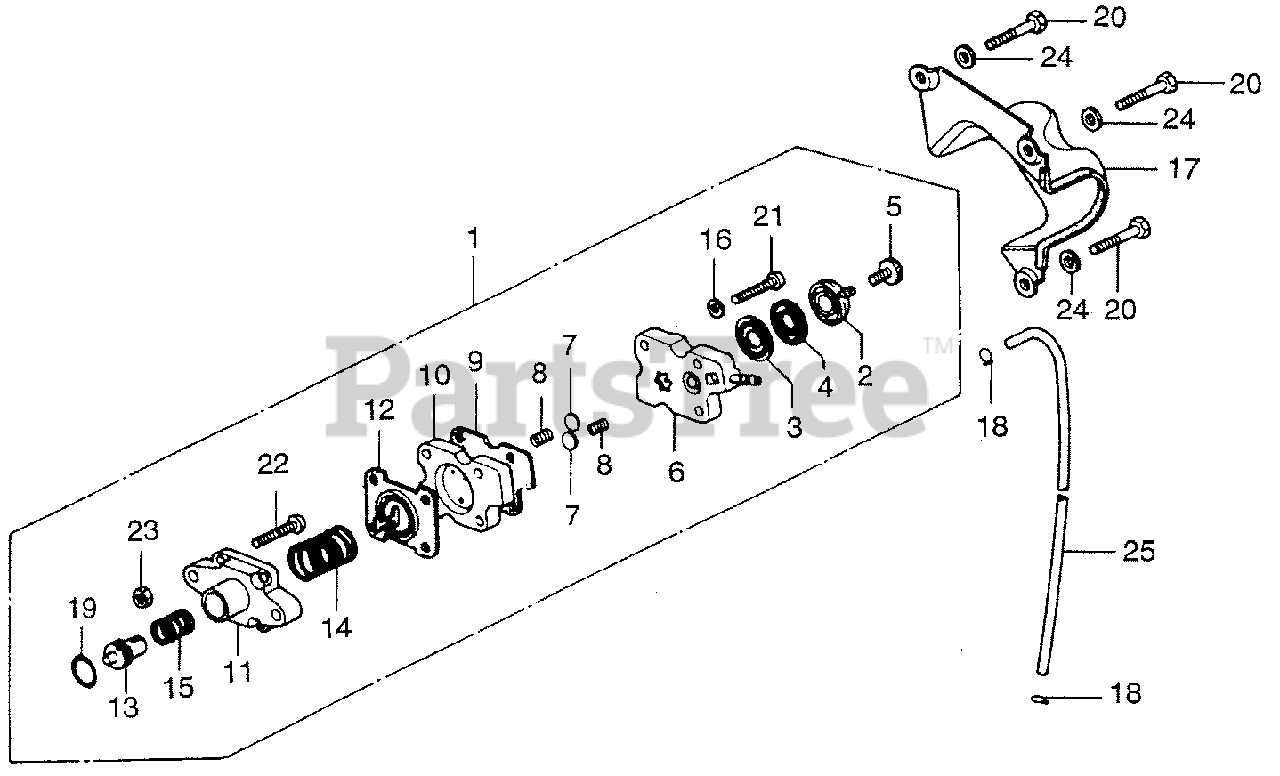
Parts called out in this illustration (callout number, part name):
1	PUMP ASSY., FUEL (NOT AVAILABLE)
2	BODY, FILTER (NOT AVAILABLE)
3	SCREEN (NOT AVAILABLE)
4	GASKET, SCREEN (NOT AVAILABLE)
5	SCREW, CAP (NOT AVAILABLE)
6	CAP (N/A: SEE ASSEMBLY) (ALT. PNO: 16700-935-325)
7	VALVE (NOT AVAILABLE)
8	SPRING, VALVE (NOT AVAILABLE)
9	GASKET, VALVE (N/A: SEE ASSEMBLY)
10	BODY (UPPER)
11	BODY (LOWER) (N/A: SEE ASSEMBLY) (ALT. PNO: 16700-935-325)
12	DIAPHRAGM (N/A: SEE ASSEMBLY) (ALT. PNO: 16700-935-325)
13	ROD, PUSH (NOT AVAILABLE)
14	SPRING, DIAPHRAGM (NOT AVAILABLE)
15	SPRING, RETURN (NOT AVAILABLE)
16	WASHER, SPRING (4MM) (NOT AVAILABLE)
17	COVER, FUEL PUMP
18	CLIP, TUBE (B8)
19	O-RING (20.8X2.4)
20	BOLT, HEX. (6X28)
21	SCREW, PAN (4X28)
22	SCREW, PAN (6X20)
22	SCREW, PAN (6X25)
23	NUT, HEX. (4MM)
24	WASHER, PLAIN (6MM)
25	BULK HOSE, FUEL (4.5X3000) (4.5X450)
